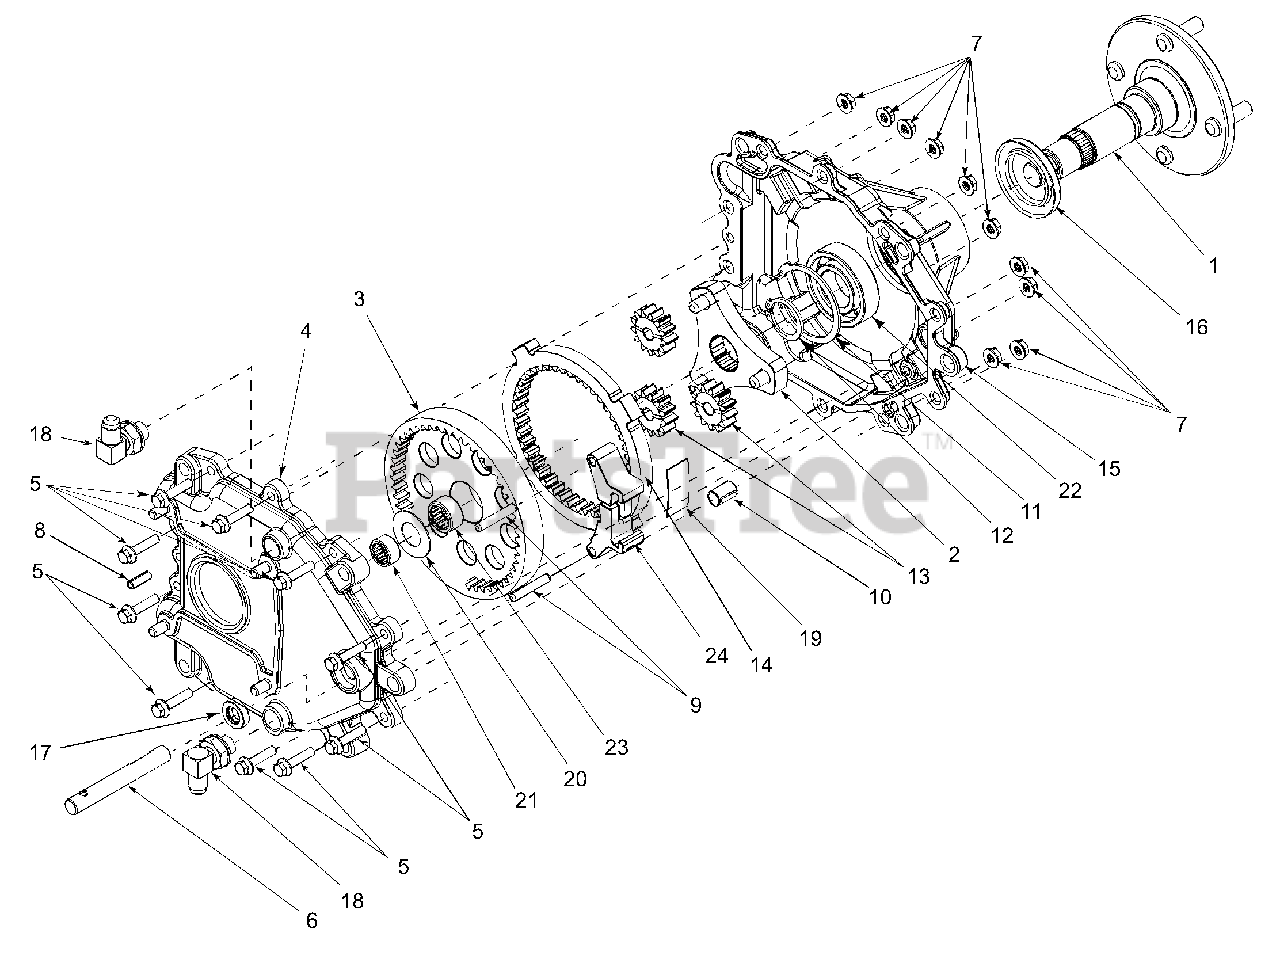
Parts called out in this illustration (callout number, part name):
1	Axle Assembly
2	Carrier Assembly, Output
3	Gear Assembly, 51T Internal & 20T
4	Housing Ass'y
5	Hex Washer Screw 1/4-20 x 1-1/8
6	Brake Shaft
7	Hex Flange Lock Nut 1/4-20
9	Dowel Pin
10	Bushing
11	Inverted Retaining Ring
12	Snap Ring
13	Spur Gear 13T
14	Ring Gear 46T
15	Axle Outer Housing
16	Oil Seal
18	Elbow Fitting
19	Brake Shoe Spring
20	Shim Washer .76 x 1.5 x .030
21	Needle Bearing
22	Ball Bearing
23	Needle Bearing
24	Shoe Brake
